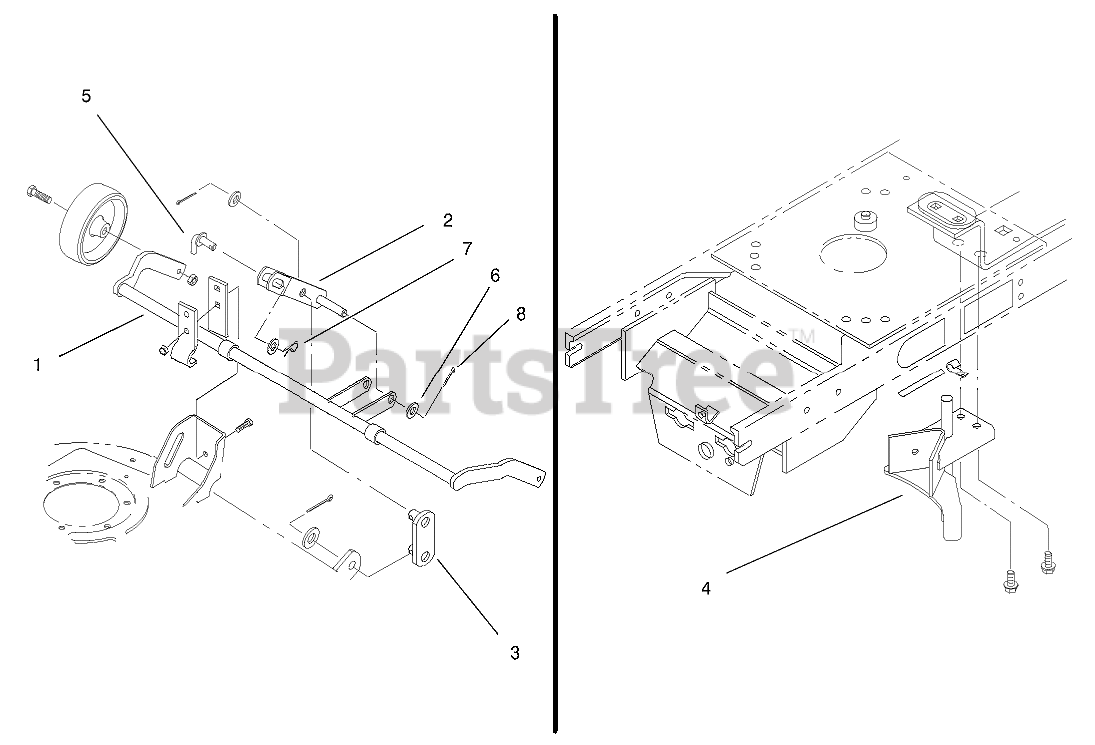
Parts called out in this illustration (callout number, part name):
1	Wheel Carrier ASM
2	LIFT ARM ASM
3	LINK BRACKET-REAR
4	DECK UPSTOP ASM
5	LINK PIN ASM
6	WASHER-FLAT
7	PIN-COTTER, HAIR
8	PIN-COTTER
